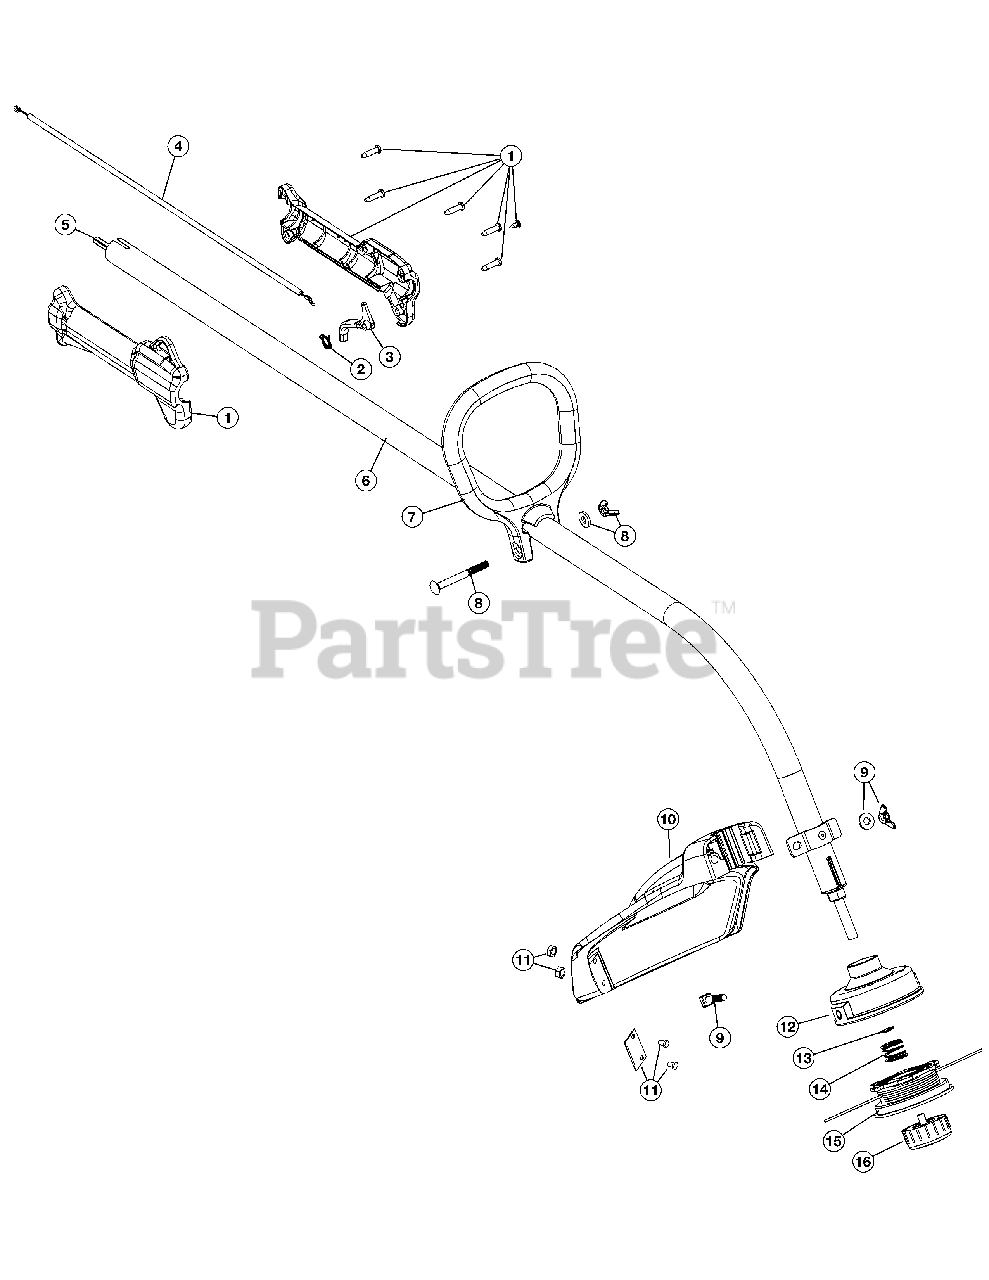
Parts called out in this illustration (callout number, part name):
1	Throttle Housing Assembly (includes 2 & 3)
2	Throttle Trigger Spring
3	Throttle Trigger
4	Throttle Cable
5	Flexible Drive Shaft
6	Drive Shaft Housing (includes 5 and 13)
7	D-Handle Assembly (includes 8)
8	D-Handle Hardware
9	Guard Mounting Hardware
10	Guard (includes 11)
11	Blade Assembly
12	Outer Reel (includes 13)
13	Retainer
15	Inner Reel (line not included)
16	Bump Knob
